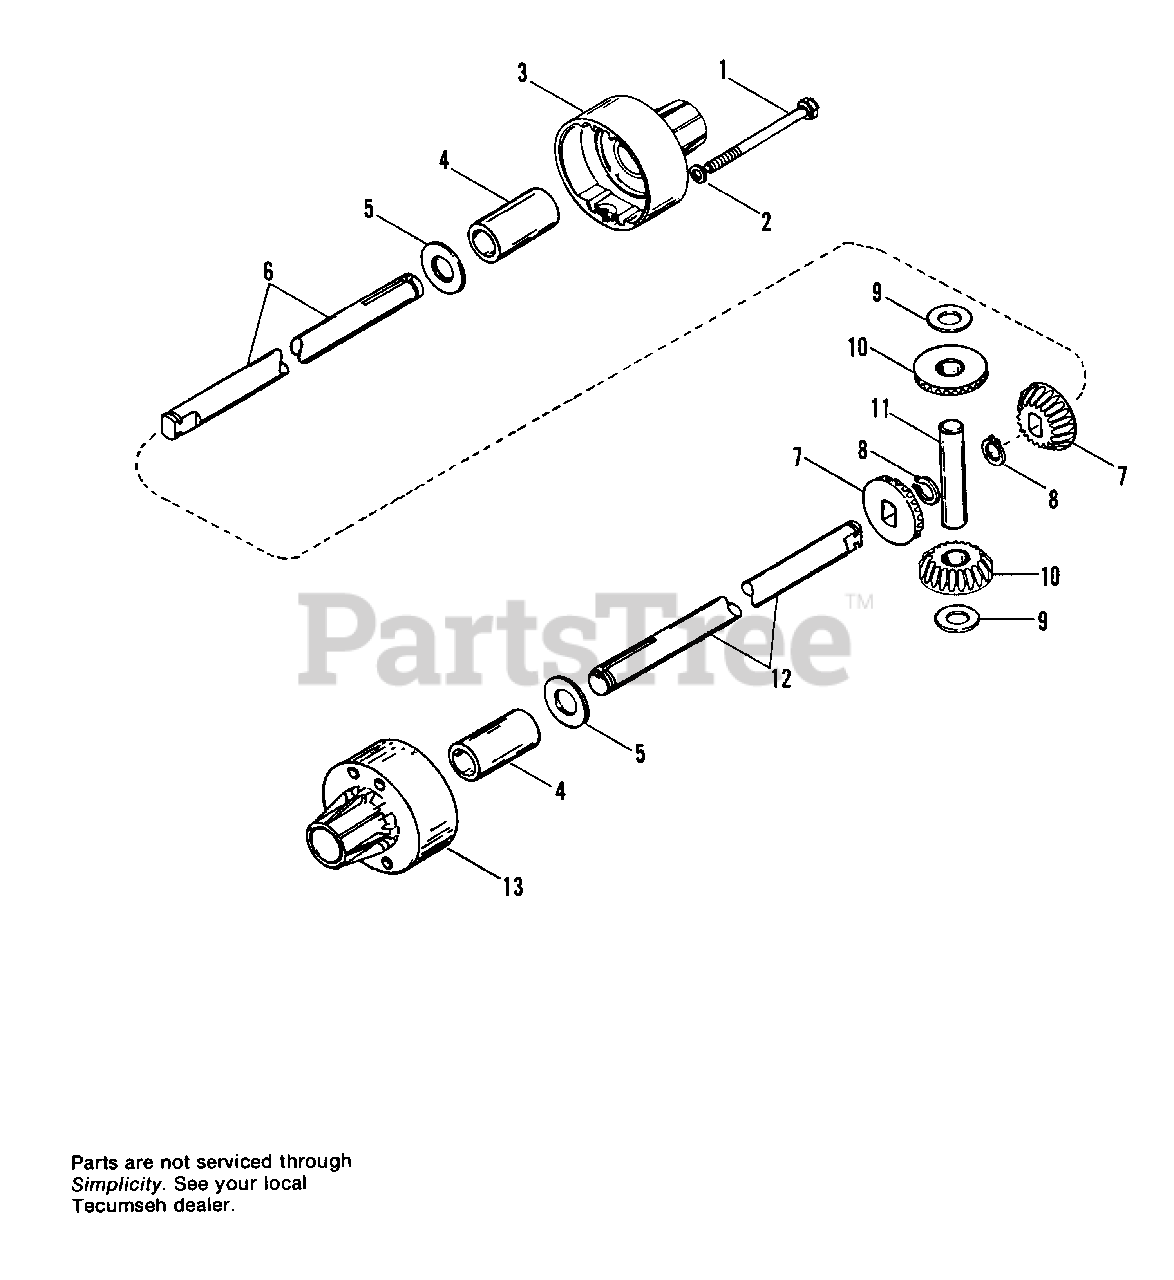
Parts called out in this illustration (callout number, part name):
1	CAPSCREW, Hex, 5/16-18 x 4
3	HOUSING, Differential (lncludes Ref. No. 4)
7	GEAR, Bevel
8	RING, Snap
9	WASHER, Thrust
10	GEAR, Pinion
11	PIN, Drive
13	HOUSING, Differential (Includes Ref. No. 4)
